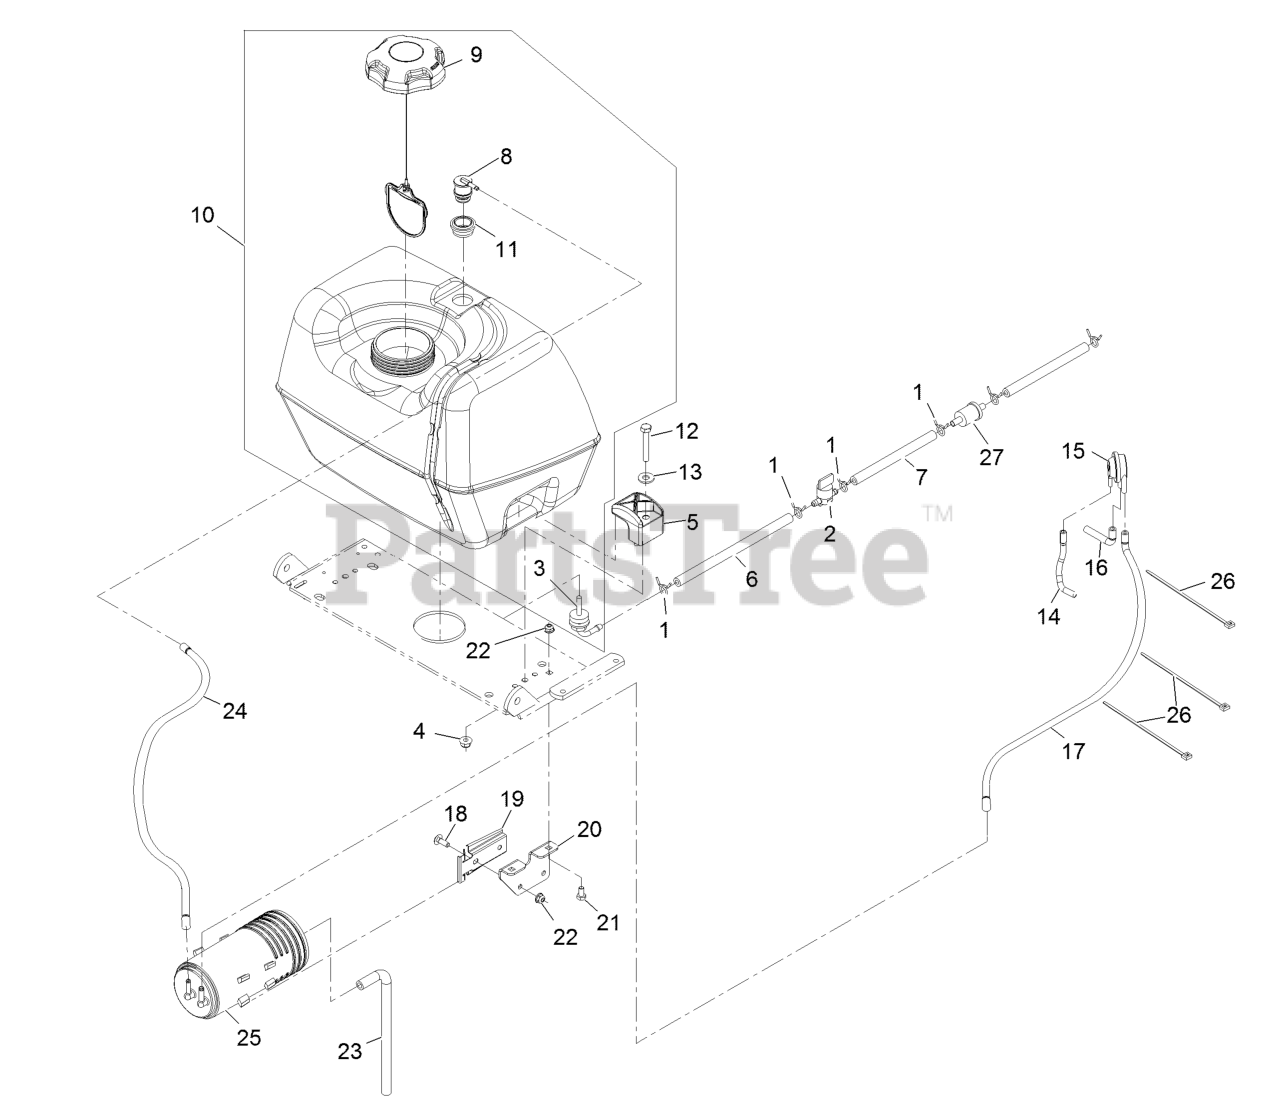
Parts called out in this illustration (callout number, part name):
1	CLAMP-HOSE
2	VALVE-FUEL
3	FITTING-FUEL, BULKHEAD
4	NUT-HF, NI
6	HOSE-FUEL
7	HOSE-FUEL
11	GROMMET
12	SCREW-HH
13	WASHER-FLAT
14	HOSE-VENT, FORMED
15	VALVE-CONTROL, VACUUM
16	HOSE-VENT, FORMED
17	HOSE-VENT, FORMED
18	SCREW-HH
19	BRACKET-CANISTER, CARBON
20	BRACKET-CANISTER, CARBON
21	BOLT-CARR
23	HOSE-VENT, CANISTER
24	HOSE-VENT
25	CANISTER-CARBON, 800CC
26	TIE-PLASTIC
27	Pn 49019-0014 Filter W/6in Fuel Line
